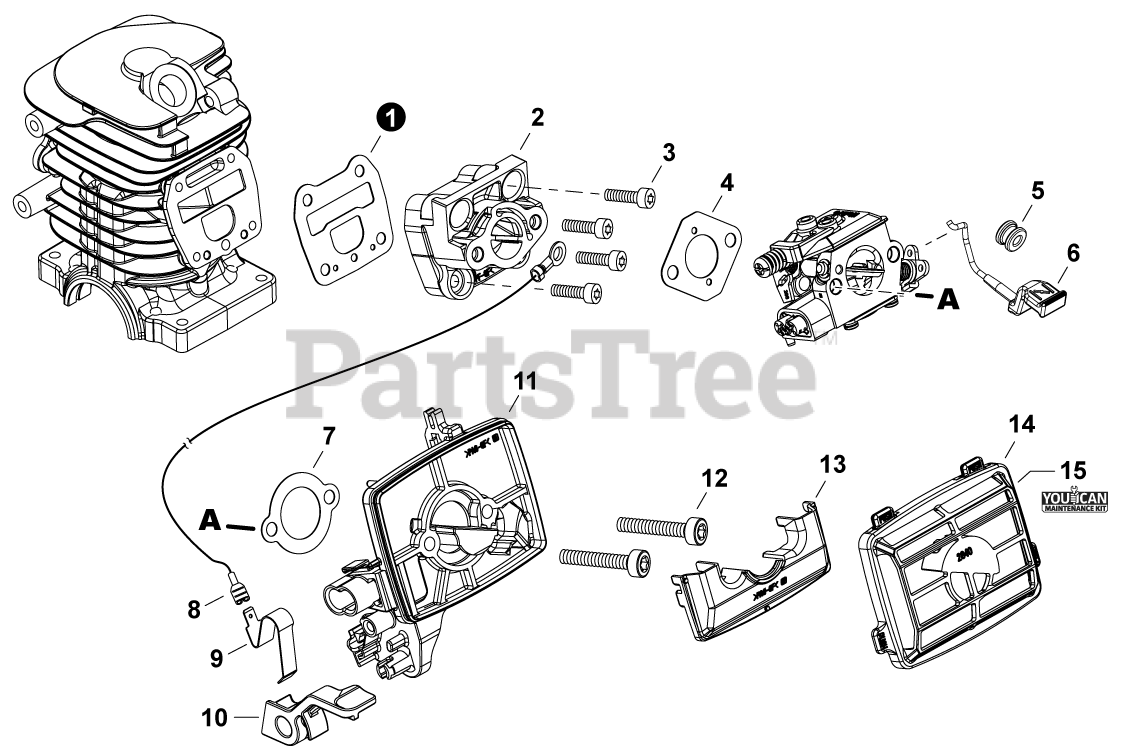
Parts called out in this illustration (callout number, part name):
1	GASKET, INTAKE
2	INSULATOR, INTAKE
3	BOLT, TORX 4x20
4	GASKET, INTAKE
5	GROMMET, CHOKE
6	KNOB, CHOKE
7	GASKET, INTAKE
9	PLATE, CONTACT
10	SWITCH, STOP
11	BRACKET, AIR FILTER
12	BOLT, TORX 5x50
13	DUCT, AIR
14	FILTER, AIR
15	TUNE-UP KIT - YOUCANT
